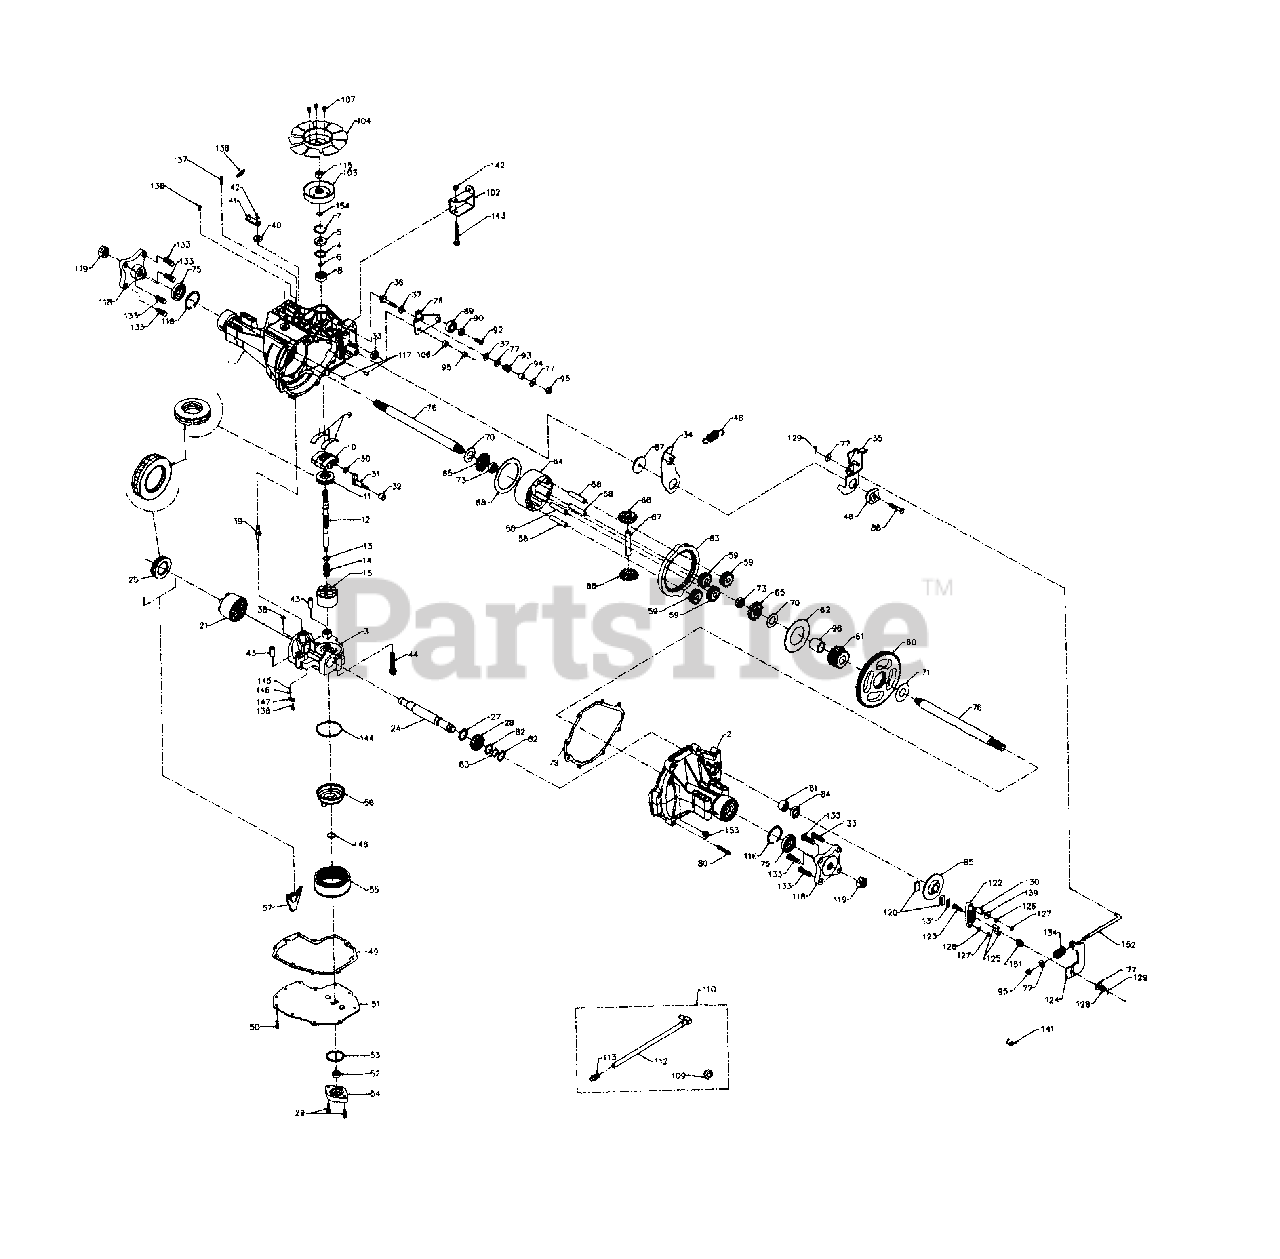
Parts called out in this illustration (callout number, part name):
1	Main Housing Ass'y.
2	R.H. Housing Ass'y.
3	Center Section Ass'y.
7	Retaining Ring
8	Ball Bearing
9	Cradle Bearing
10	Variable Swashplate
11	Thrust Bearing
12	Input Shaft
13	Block Thrust Washer
14	Block Washer
15	Cylinder Block Ass'y.
21	Cylinder Block Ass'y.
24	Output Shaft
25	Thrust Bearing
26	Control Arm
27	Spacer
28	16T Pinion Gear
29	Capscrew M6 x 1-20
30	Slot Guide
31	Trunnion Arm
32	Trunnion Bushing
34	Return Arm
35	Actuating Arm
36	Stud 5/16-24 Thd.
37	Friction Puck
38	Bypass Plate
39	Bypass Actuator
41	Bypass Arm
42	Retaining Ring
44	Screw
46	Neutral Spring
48	Adjusting Spring
49	Lower Gasket
50	Self-Tapping Screw
51	Lower Cover
52	Gerotor Ass'y.
54	Gerotor Cover
55	Filter
56	Charge Manifold
57	Retainer, Motor Bearing
58	Pin, Carrier
59	15T Planet Gear
60	67T Spur Gear
61	21T Sun Gear
62	Planet Thrust Plate
63	51T Ring Gear
64	Planetary Carrier
65	Miter Gear
66	Miter Gear
67	Shaft, Differential
68	Differential, Thrust Plate
70	Washer
71	Washer
73	Hex Jam Nut 5/8-18 Thd.
75	Seal
76	Shaft, Axle
77	Washer
79	Gasket, Main Housing
80	Torx Hd. Scr. 5/15-18 Thd.
81	Needle Bearing
82	Washer
83	Retaining Ring
85	Brake Disk
87	Washer
88	Screw 5/16-24 x 1.75" Lg.
89	Bearing
90	Spacer, Locating
92	Countersunk Screw
93	Spring
94	Spacer
95	Hex L-Nut 5/16-24 Thd.
96	Sleeve Bearing
102	Torque Bracket
103	Pulley
106	Spacer, Trunnion
107	Screw
109	Vent Bushing
110	Fitting Kit
112	Hose Fitting Ass'y.
113	Cap-Vent Ass'y.
115	Jam Nut
116	Retaining Ring
117	Std. Handle Pin
119	Hex Nut 3/4-16 Thd.
120	Puck, Brake
122	Brake, Yoke
123	Bolt, Square Head
124	Arm, Brake
125	Pin, Brake
126	L-Wash. 1/4" I.D.
127	Hex Nut 1/4-20 Thd.
128	Castle Nut
129	Cotter Pin
130	Spacer
131	Puck Plate
133	Wheel Stud
134	Brake Spring
136	Extension Spring
137	Spring Pin
138	Screw, Self-Tapping 10-32 x .5"
139	Washer .265" I.D. x .875" O.D.
141	Spring, Brake
142	Hex L-Nut 5/16-18 Thd.
143	Bolt 5/16-18 x 2.5" Lg.
144	O-Ring
145	Relief Spring
147	Plate, Relief
148	O-Ring
151	Brake Comp. Spring
152	Brake Pull Rod
154	Wire Retaining Ring
